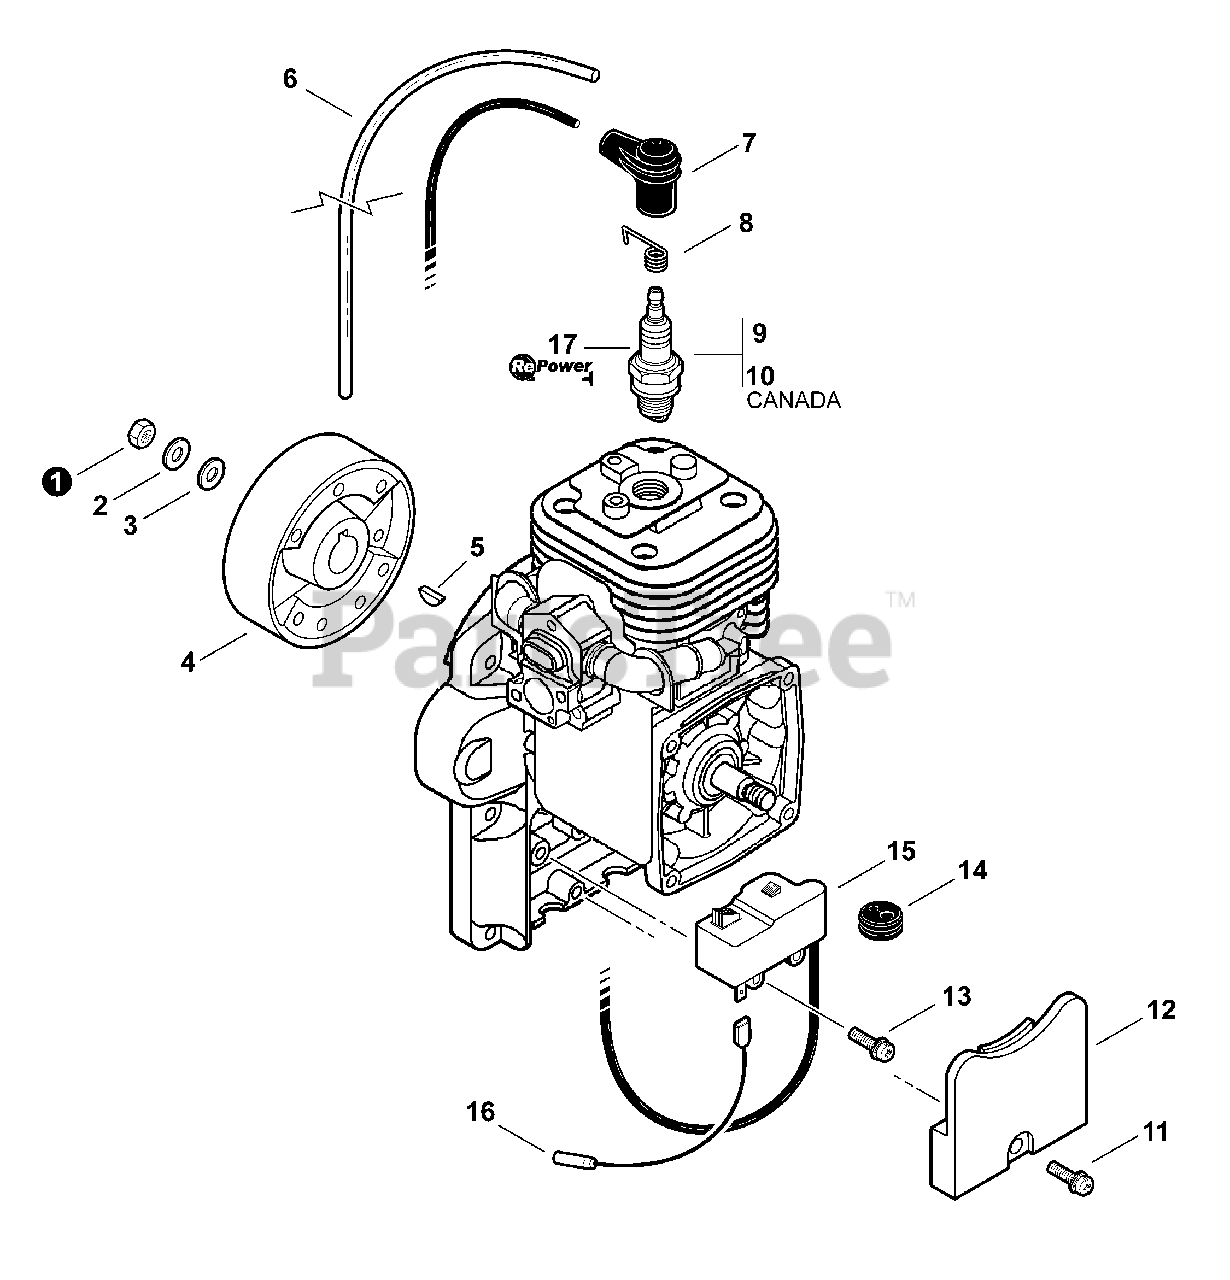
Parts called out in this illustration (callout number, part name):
1	NUT - 10
2	LOCKWASHER - 10
3	WASHER - 10
4	FLYWHEEL
5	KEY - 3×14
6	TUBE - VINYL
7	CAP, SPARK PLUG
8	TERMINAL, SPARK PLUG CAP
9	SPARK PLUG -- BPM8Y
10	SPARK PLUG -- BPMR8Y
11	SCREW - 5×18
12	COVER, DUST
13	SCREW - 5×18
15	COIL, IGNITION
16	LEAD - IGNITION
17	RePower TUNE-UP KIT
